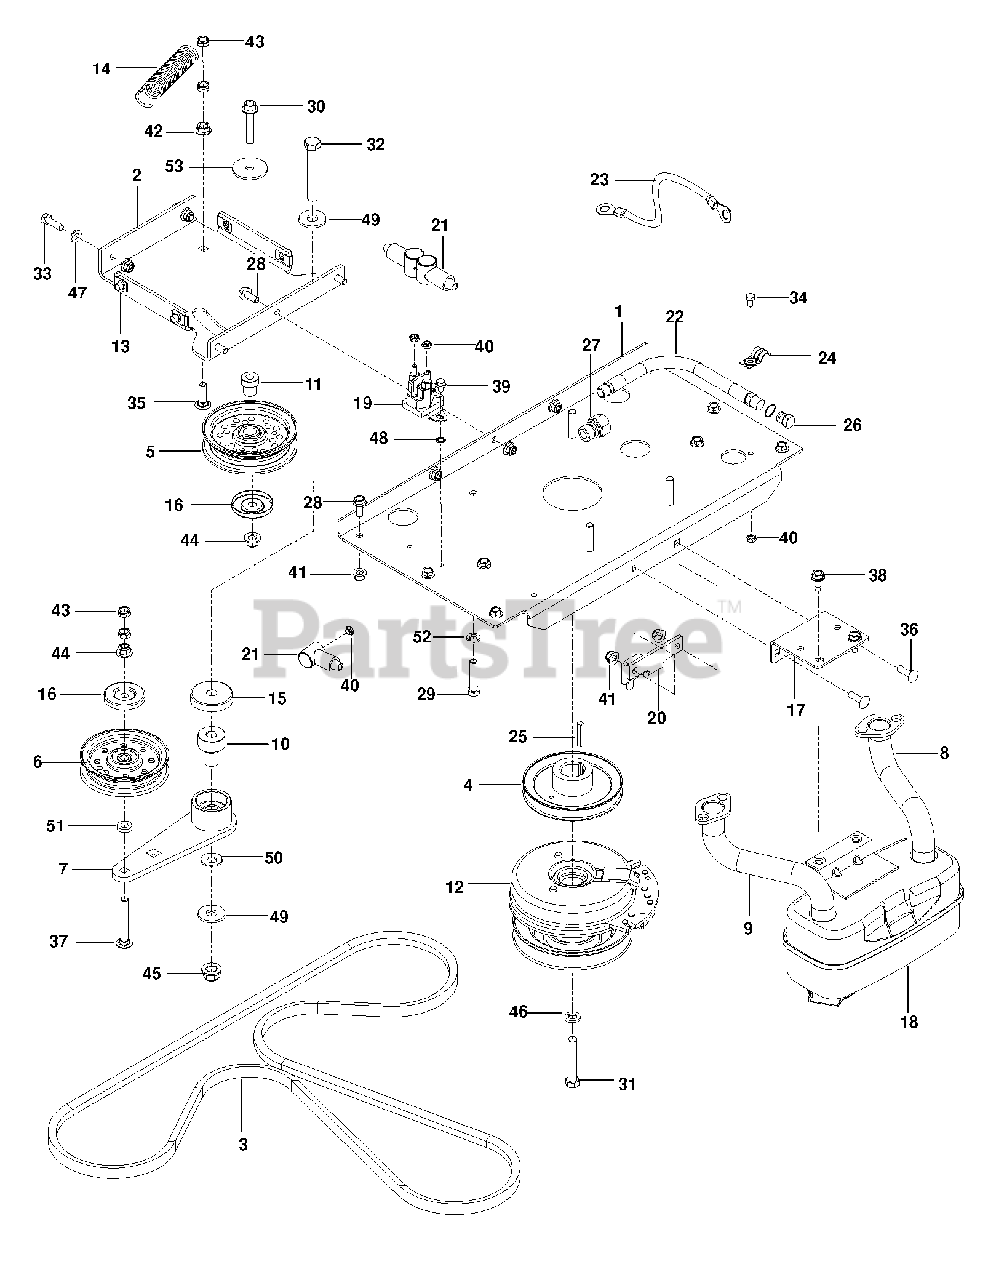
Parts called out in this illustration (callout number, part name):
2	PLATE, IDLER, BLK
3	BELT, HYDRO, 3400
4	PULLEY, V, 1.125 BORE
5	IDLER PULLEY
7	ARM, IDLER, STEEL, W/BGS
10	PIVOT, BEARING
11	PIVOT, IDLER
12	CLUTCH 200 FT LB
13	U-CLIP 5/16-18 NUT RETAINER
14	SPRING, PUMP
15	SHIELD, DUST
16	DUST SHIELD
18	MUFFLER ASM TWIN
19	SOLENOID
21	INSULATOR
23	CABLE POSITIVE
25	KEY, 1/4 SQ X 1 1/4
27	ADAPTER, OIL DRAIN
28	HHFS 5/16-18 X 3/4
29	BOLT, HCS 3/8-16X1-3/4
30	HHFS 3/8-16 X 2.0 GD 5
32	HCS 1/2C X 3 1/4
33	HCS 5/16C X 1
34	HCS 1/4-20.
35	RHSNB 3/8-16 X 1-1/4
36	RHSSNB 5/16C X 1.0
37	RHSNB 3/8-16 X 2.75
38	BOLT 5/16-18 X 3/4
39	HWST 1/4C X 3/8
40	JAM NUT 1/4C
41	5/16-18 NYLOC FLANGE NUT
42	NUT 3/8C WHIZ
43	NUT HEX 3/8-16 NYLON, THIN
44	NUT 3/8-16 HEX FLG NYLOC ZD
45	NUT, 1/2-13 HEX FLG NYLOC ZD
46	WASHER 7/16 LOCK
47	FLAT WASHER 5/16 SAE
48	WASHER 1/4 INT TOOTH
49	WASH USS FLAT 1/2
50	CONTACT BELLSPR 1/2
51	WASHER 3/8 X 3/4 X .187 TK
52	SLW 3/8 STD
53	WASHER, 3/8 SPEC
